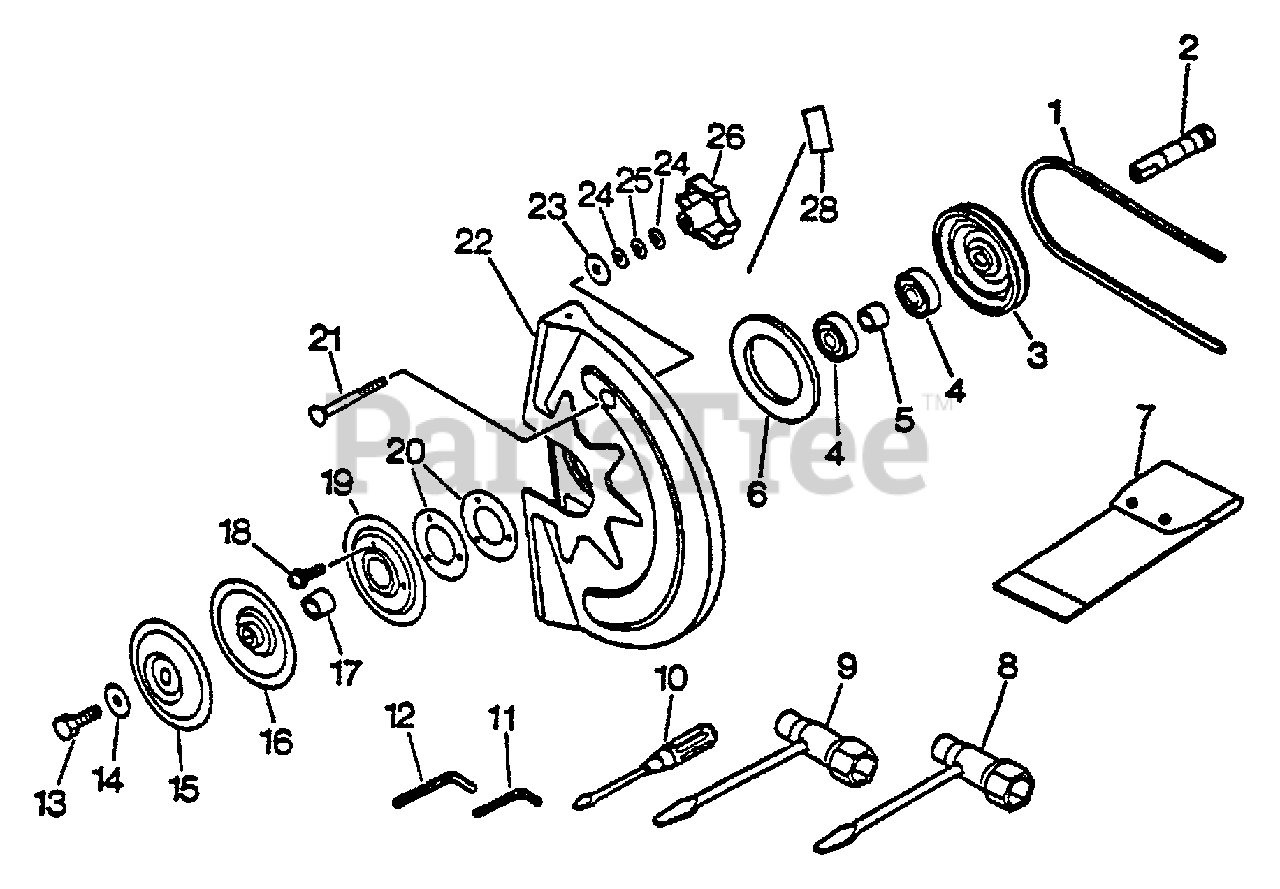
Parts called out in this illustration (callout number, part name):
4	BEARING, BALL 6203
5	SPACER
7	BAG, TOOL
8	T-WRENCH 13×19×180
9	WRENCH, T 17×19 MM
10	SCREWDRIVER, SLOTTED
11	WRENCH, ALLEN 4 MM
12	WRENCH, ALLEN 5 MM
15	FLANGE, CUTTER
16	FLANGE, CUTTER
18	SCREW 4×14
19	PLATE
22	COVER, BLADE
24	WASHER 10.5×18×1.6
25	WASHER, SPRING 10
28	LABEL - ECHO
